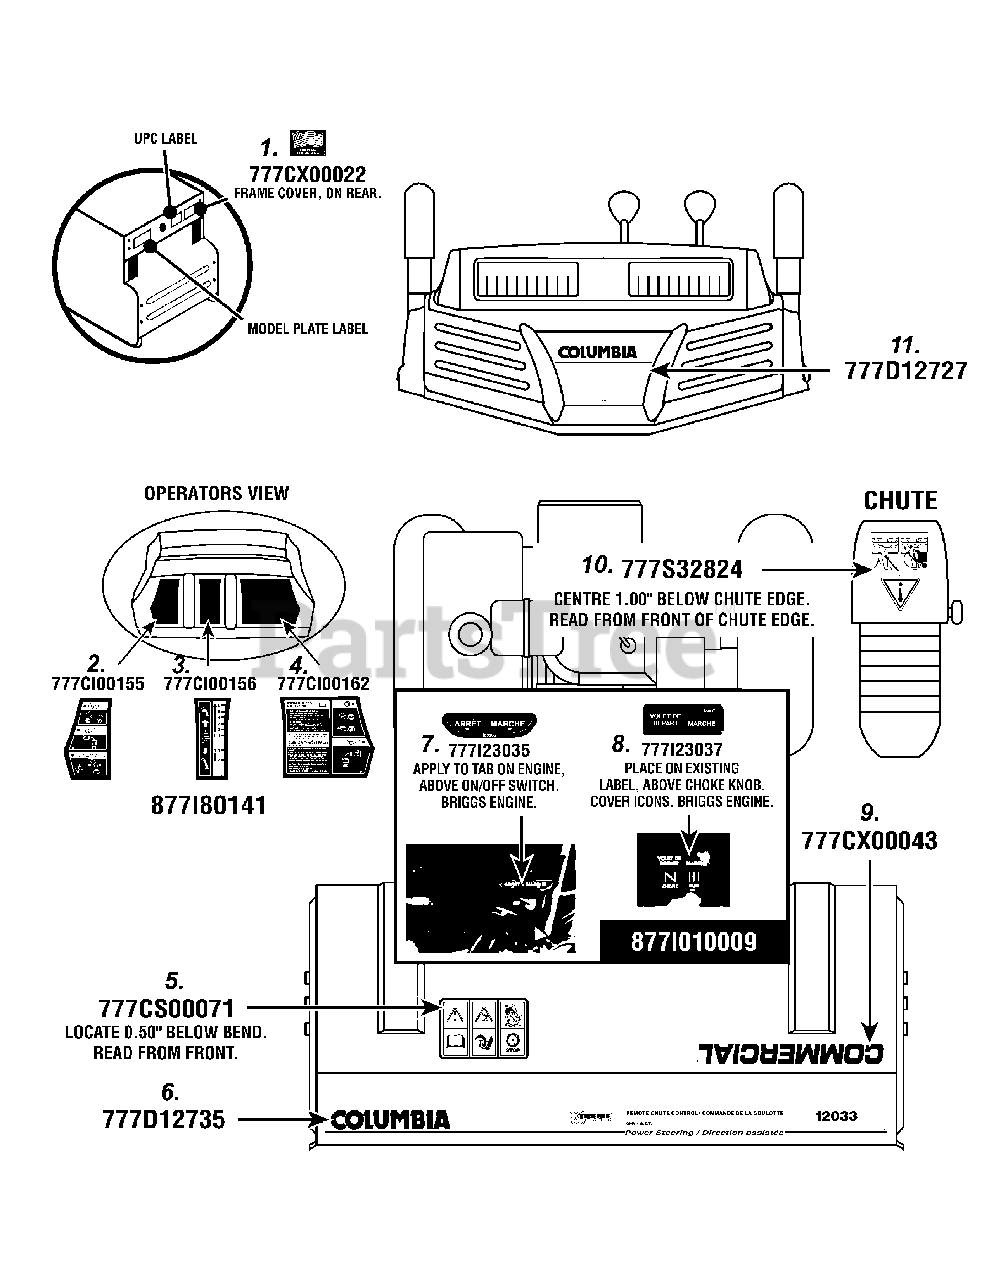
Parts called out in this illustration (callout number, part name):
1	LABEL- MADE IN USA
2	LABEL-SNOW:CNTRLPNL:STY7:LH
3	LABEL-SNOW:CNTRLPNL:STY7:MDL
4	LABEL-SNOW:CNTRLPNL:STY7:RH
4	LABEL-UV HOT SURFACE
5	LABEL-DANGER AUGER
6	LABEL-SNOW:HSG:9J76:33:597
7	LABEL-SNOW:B&S ENG:ON/OFF:FRN:CDN
8	LABEL-SNOW:B&S EN:CHK/RUN:FRN:CDN
9	LABEL-COMMERCIAL
10	LABEL-SNOW:CHUTE:ADHSV EXP
11	LABEL-COLUMBIA
